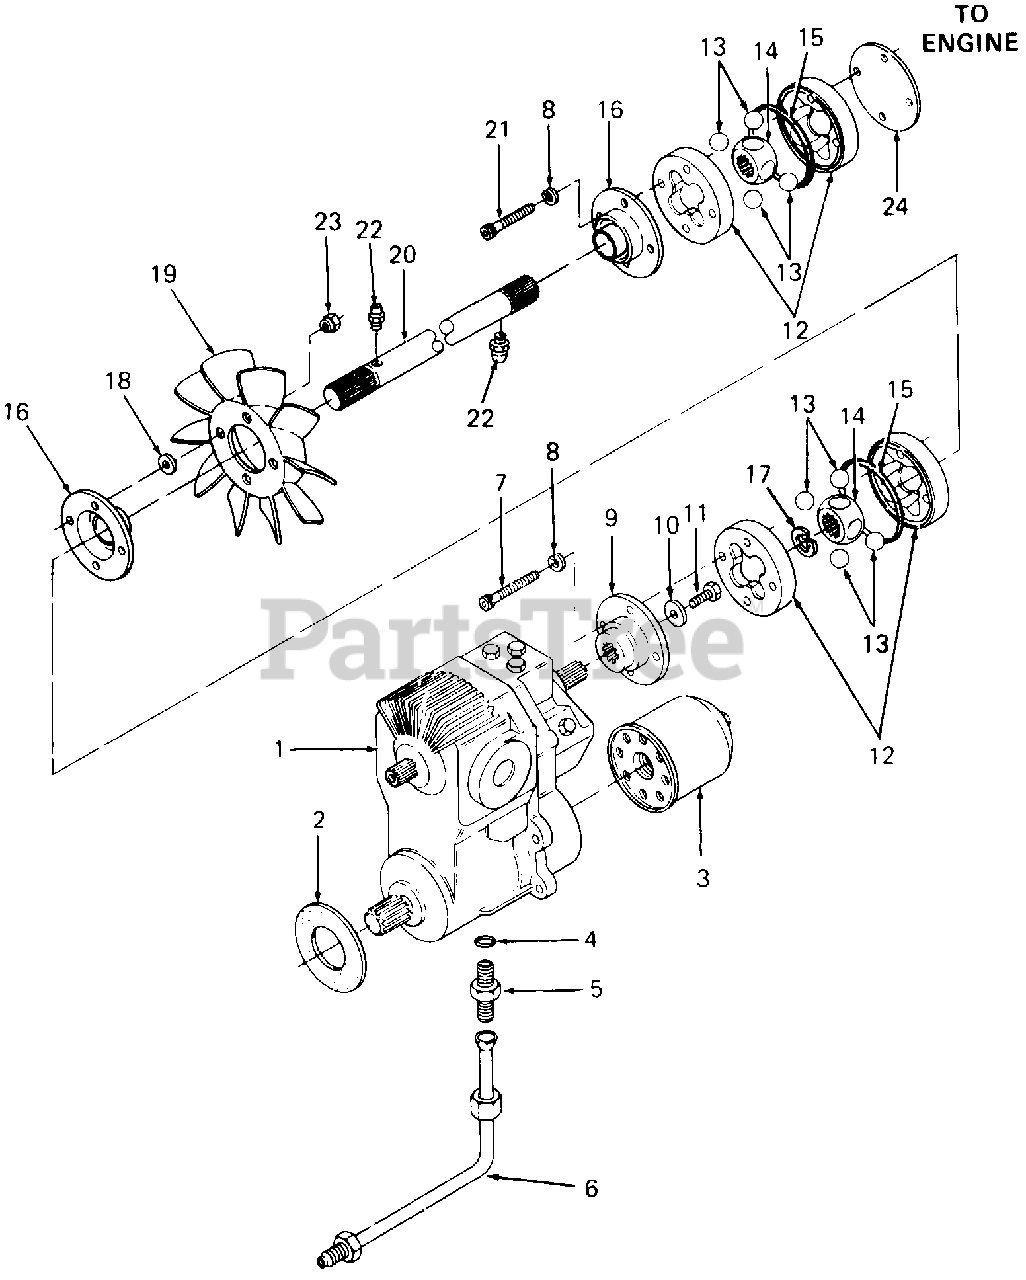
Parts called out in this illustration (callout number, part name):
1	Pump, Hydrostatic
2	Gasket, Front
3	Filter, Oil
4	O-Ring, 5/8 OD Tube
5	Connector, 37 Degree
6	Tube Assy
7	Screw, Socket Hd Cap, 1/4-20 X 2.0 Lg
8	Washer, Lock, 1/4
9	Adapter, Pump
10	Washer, Bell, .265 X .75 X .062 Thk
11	Bolt, Hex Patch, 1/4-20 X 1.0 Lg GR5
12	Coupling, Drive w/O-Ring Groove
13	Ball, Steel, 5/8 Dia Chrome
14	Hub, Drive
15	O-Ring, 2.489 X.070
16	Boot, Coupling
17	Ring, Snap
18	Washer, Flat, .25 X .62 X .052 Thk
19	Fan, 10 Blade Hydro
20	Shaft, Drive, 23.9 Lg
21	Screw, Socket Hd Cap, 1/4-20 X 1.75 Lg
22	Fitting, Grease
23	Nut, Fan 1/4-20
24	Cover, Coupling
